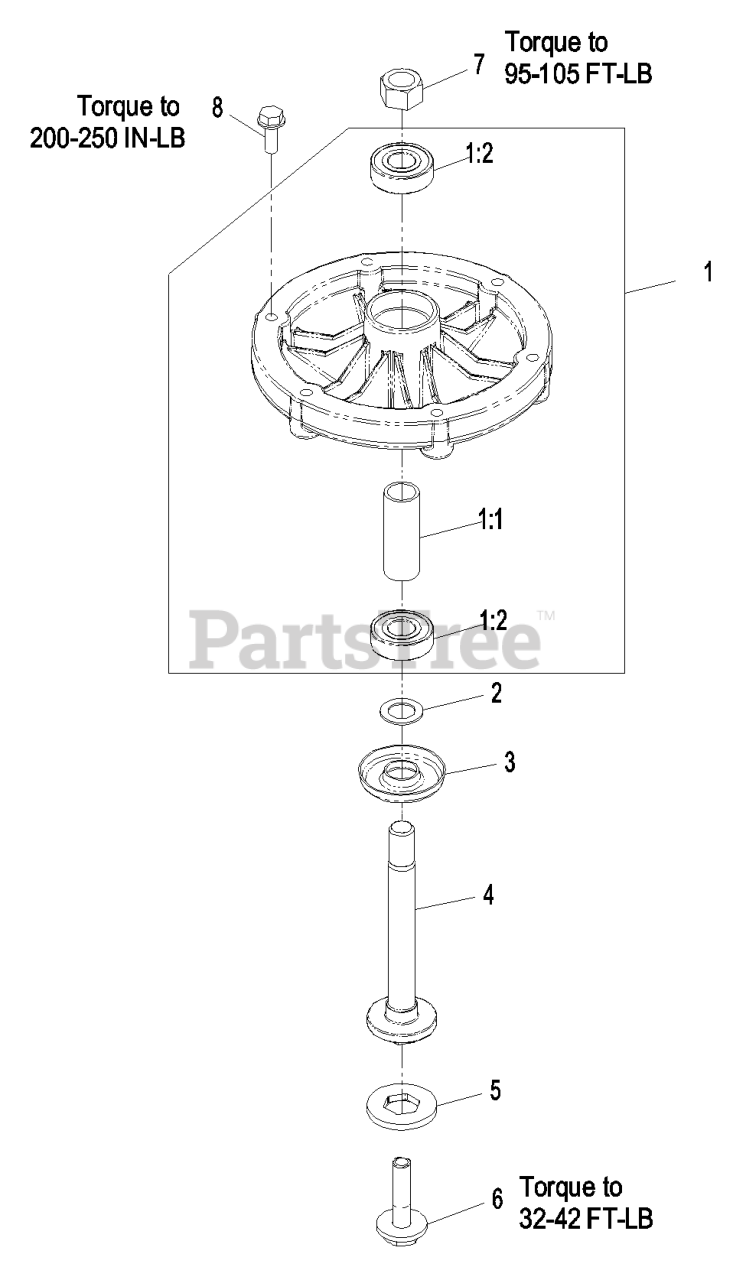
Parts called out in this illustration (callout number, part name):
1:2	BEARING-BALL
3	SHIELD-BEARING
4	SPINDLE-HEX PILOT
5	WASHER-BLADE DRIVE
6	BOLT-BLADE, SEM
7	NUT-HEX
8	SCREW-TAPTITE
